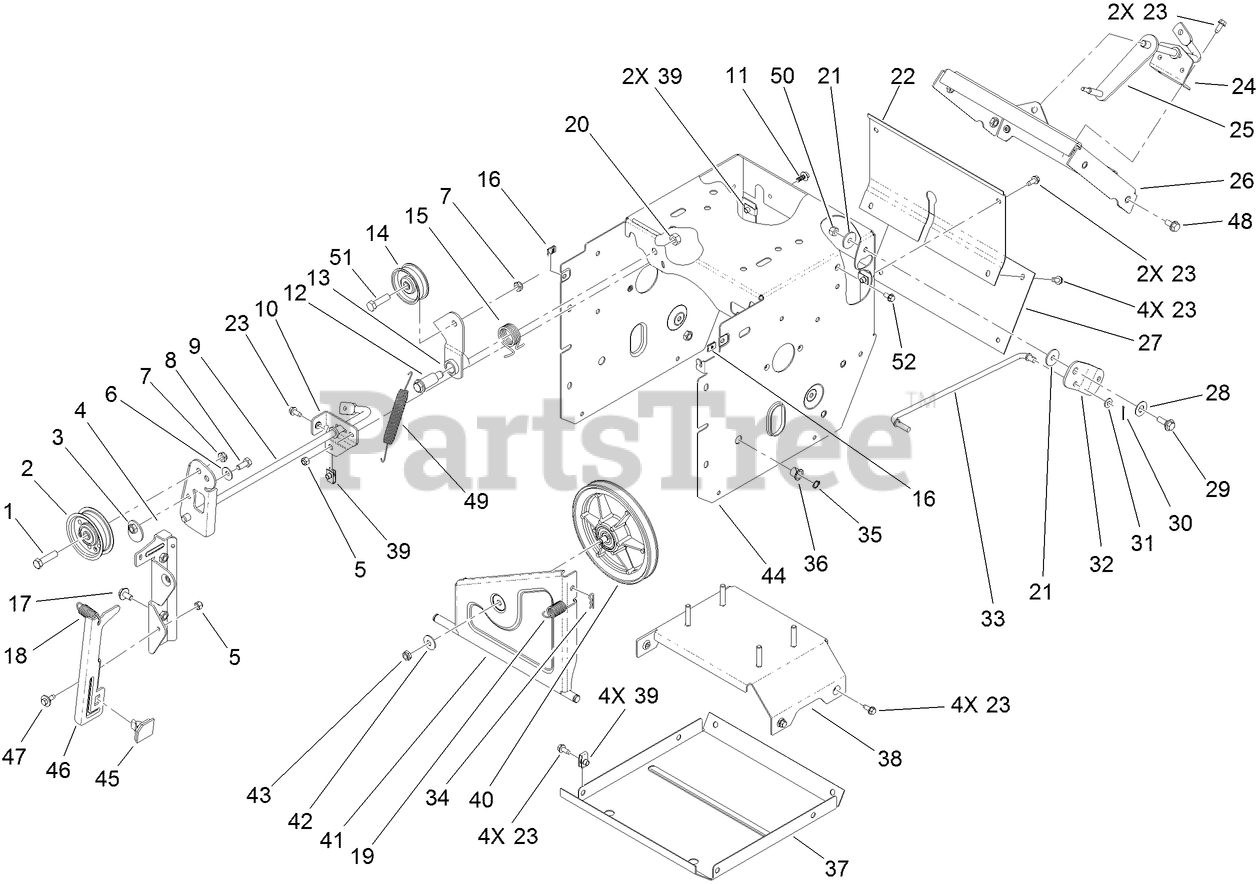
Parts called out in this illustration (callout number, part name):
1	SCREW-HH
2	PULLEY-IDLER
5	NUT-LOCK, NI
6	WASHER-BELLEVILLE
8	SCREW-HH
9	IMPELLER CLUTCH ASM
10	BRACKET-CLUTCH, IMPELLER
11	SCREW-HHF
12	BOLT-SHOULDER
13	ARM-IDLER, TRACTION
14	PULLEY-IDLER
15	SPRING-TORSION
16	NUT-SPEED
17	SCREW-HHF
18	SPRING-EXTENSION
19	SPRING-EXTENSION
20	NUT-LOCK, NI
21	WASHER-PIVOT
22	COVER-UPPER
23	SCREW-HWH
24	BRACKET-ROD, SHIFT
25	LEVER-CONTROL, TRACTION
26	SHIFT PLATE ASM
27	COVER-LOWER
28	WASHER
29	SCREW-SHOULDER
30	PIN-COTTER
31	WASHER-PLAIN
32	BELLCRANK-DRIVE
33	LINK-CONTROL, SPEED
35	RING-RETAINING
36	BUSHING-NYLINER
37	PAN-BOTTOM
38	FRAME BRACE ASM
40	PULLEY-TRACTION
41	BRACKET-WHEEL, FRICTION
42	WASHER-BELLEVILLE
43	NUT-HEX
44	FRAME-TRACTION
45	PAD-BRAKE
47	SCREW-SHOULDER
48	SCREW-HWHTF
50	NUT-LOCK, NI
51	SCREW-HH
52	SCREW-HWH
